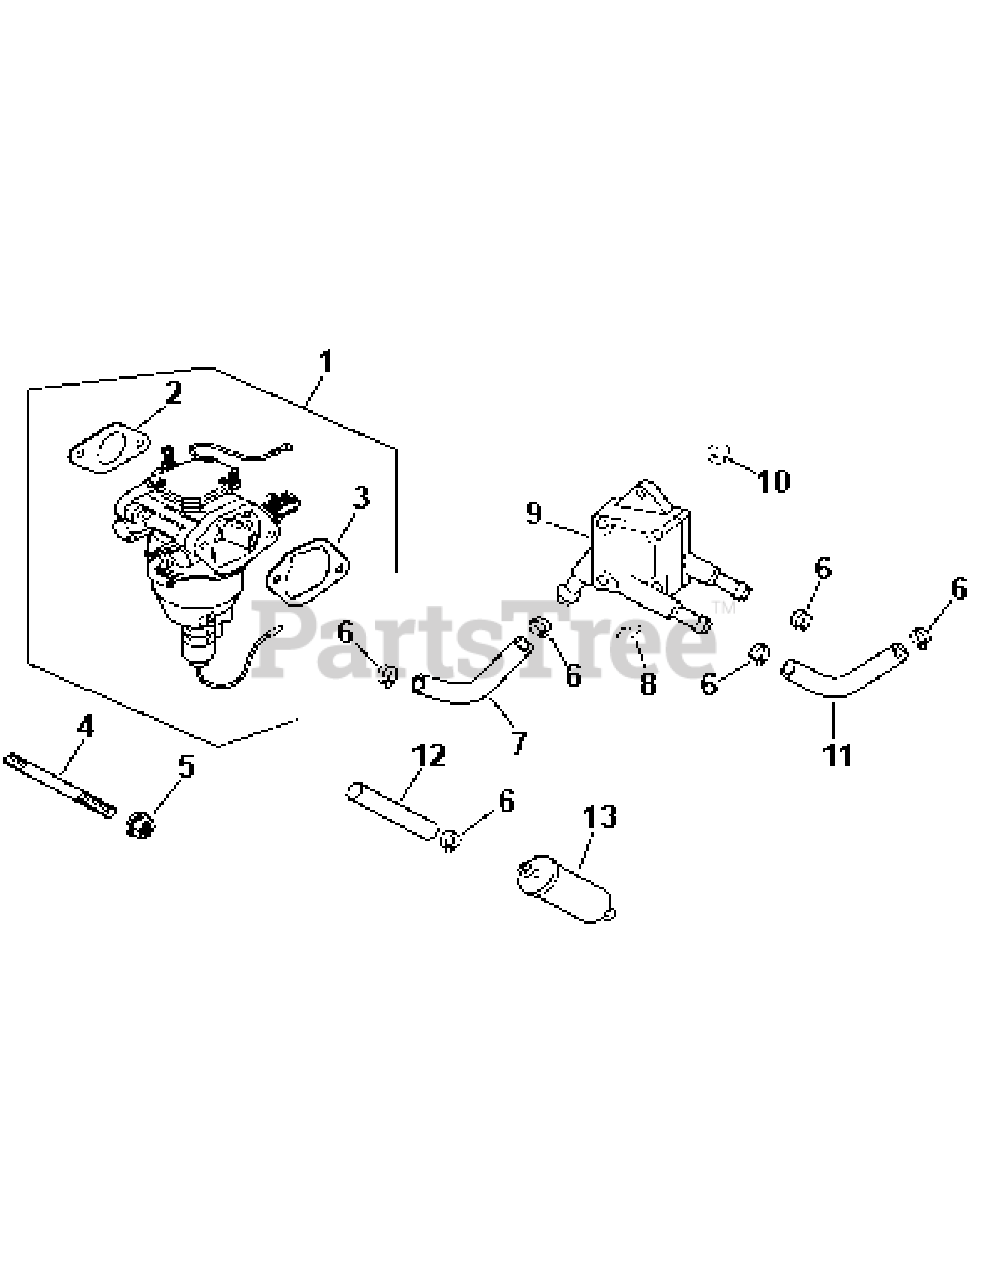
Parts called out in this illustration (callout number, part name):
1	Carburetor w/Gaskets
2	Carburetor Gasket
3	Air Cleaner Base Gasket
4	Intake Manifold Stud
6	Hose Clamp
7	Fuel line 12.5"
10	Plastic Nut
11	Fuel Line 11"
12	Fuel Line 11.5"
13	Fuel Filter
